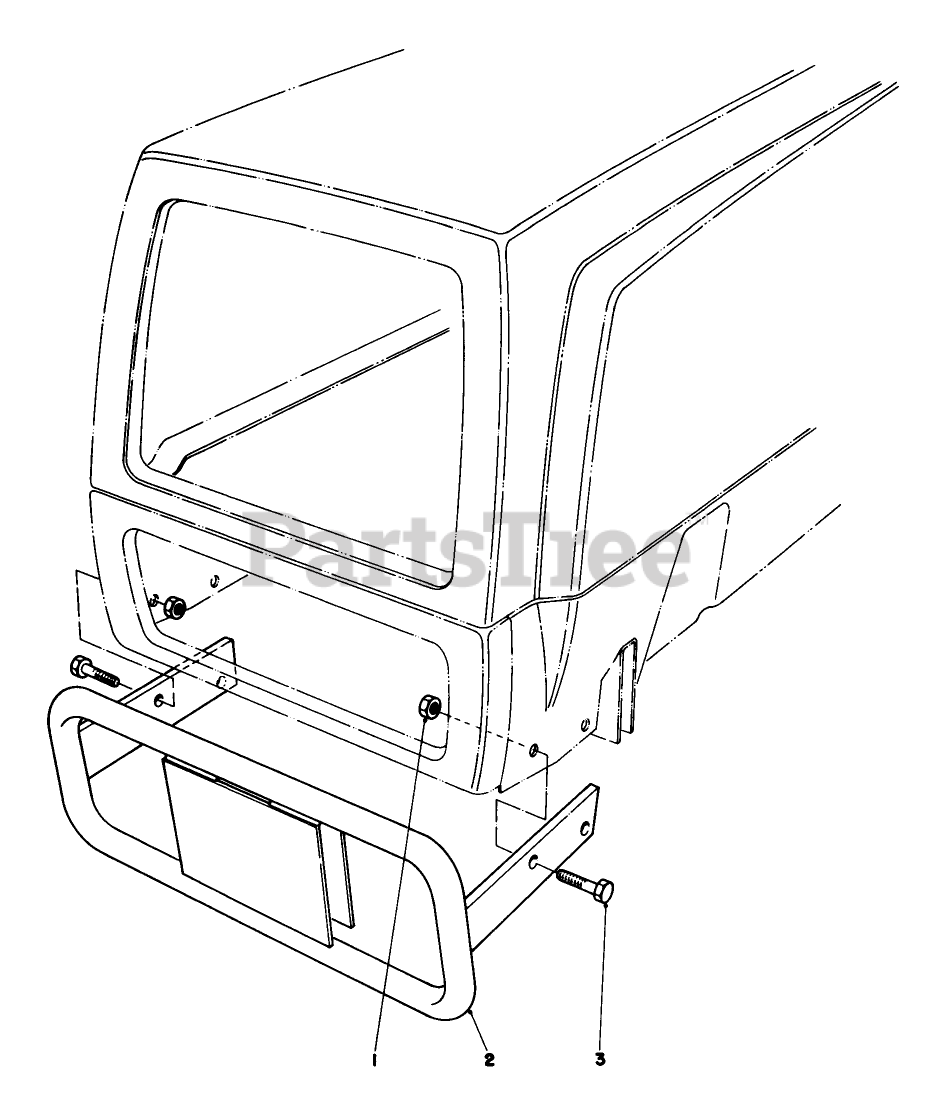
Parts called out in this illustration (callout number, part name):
1	NUT-LOCK, CONE
2	Bumper
3	SCREW-HH
